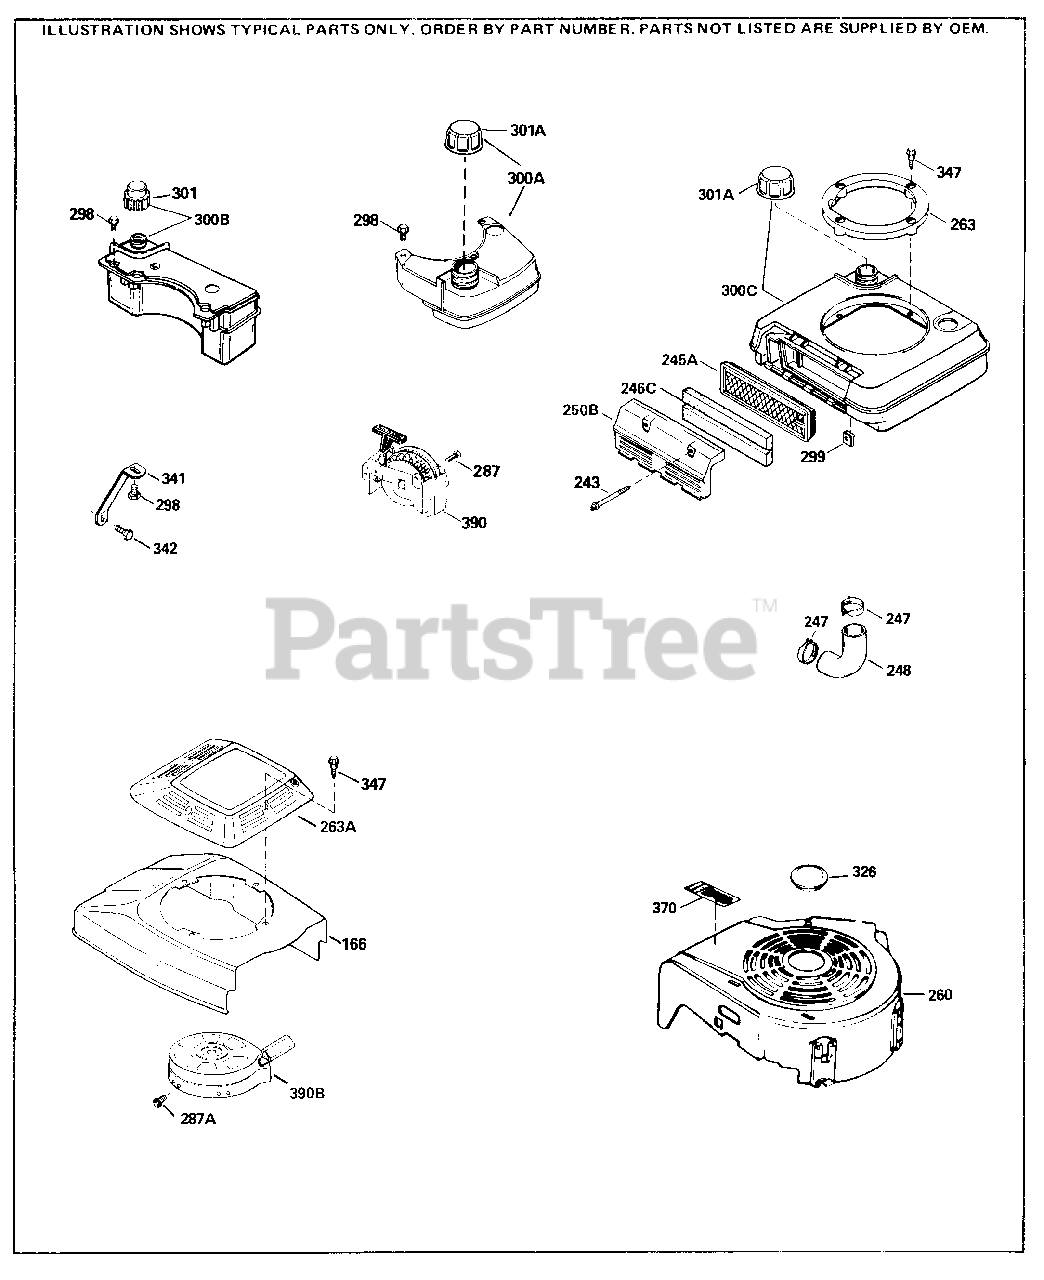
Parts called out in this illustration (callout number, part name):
65	Screw, 10-24 X 9/16"
110A	Ground Wire (10.50" With Male & Femal e Flag Terminals)
260	Blower Housing
287	Screw, 8-32 X 21/64"
301	Fuel Cap (Black) (1-1/2" I.D.)
355	Starter Handle (Standard)
370	Decal - Tecumseh Logo For Top Of Reco il Starter
390	Rewind Starter
